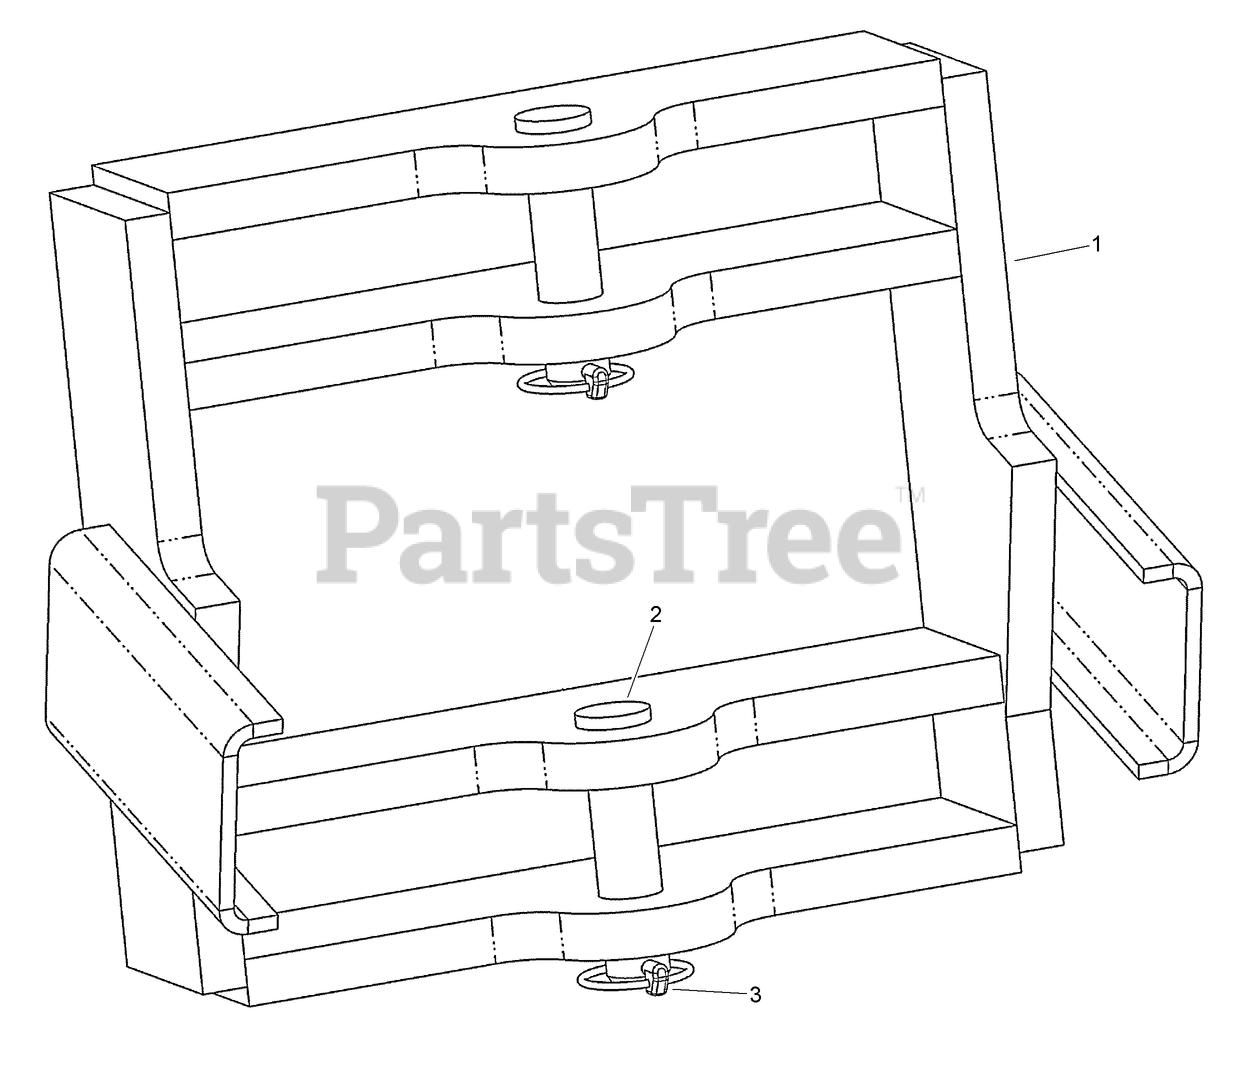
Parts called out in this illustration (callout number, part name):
1	WELDMENT - Rear Trencher Mount1
2	PIN-PIVOT
3	PIN-KLIK
